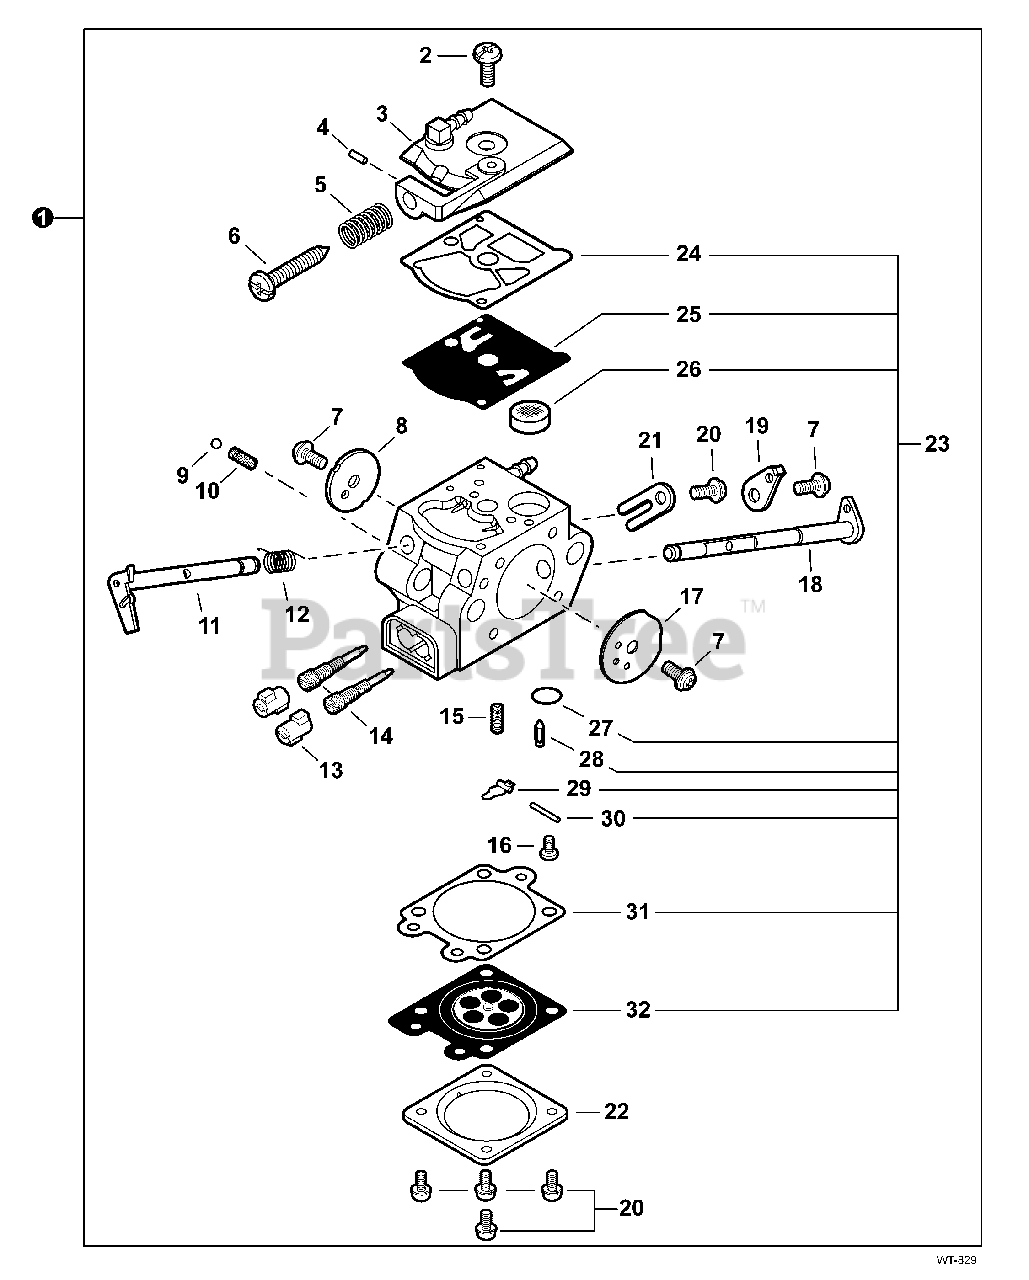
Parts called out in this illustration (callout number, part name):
1	CARBURETOR - WT-829
3	COVER, FUEL PUMP
4	PLUG, FRICTION
5	SPRING, IDLE ADJUST
6	SCREW, IDLE ADJUST
8	VALVE, THROTTLE
9	BALL, CHOKE FRICTION
11	SHAFT ASSY, THROTTLE
12	SPRING, THROTTLE RETURN
13	CAP, LIMITER
14	NEEDLE, MIXTURE
15	SPRING, METERING LEVER
16	SCREW, METERING LEVER PIN
17	VALVE, CHOKE
18	SHAFT, CHOKE
19	LEVER, THROTTLE
21	CLIP, THROTTLE SHAFT
22	COVER, METERING DIAPHRAGM
23	REPAIR KIT, CARBURETOR
24	GASKET, PUMP
25	DIAPHRAGM, PUMP
26	SCREEN, INLET
27	PLUG, WELCH
28	VALVE, INLET NEEDLE
29	LEVER, METERING
30	PIN, METERING LEVER
31	GASKET, METERING DIAPHRAGM
32	DIAPHRAGM, METERING
